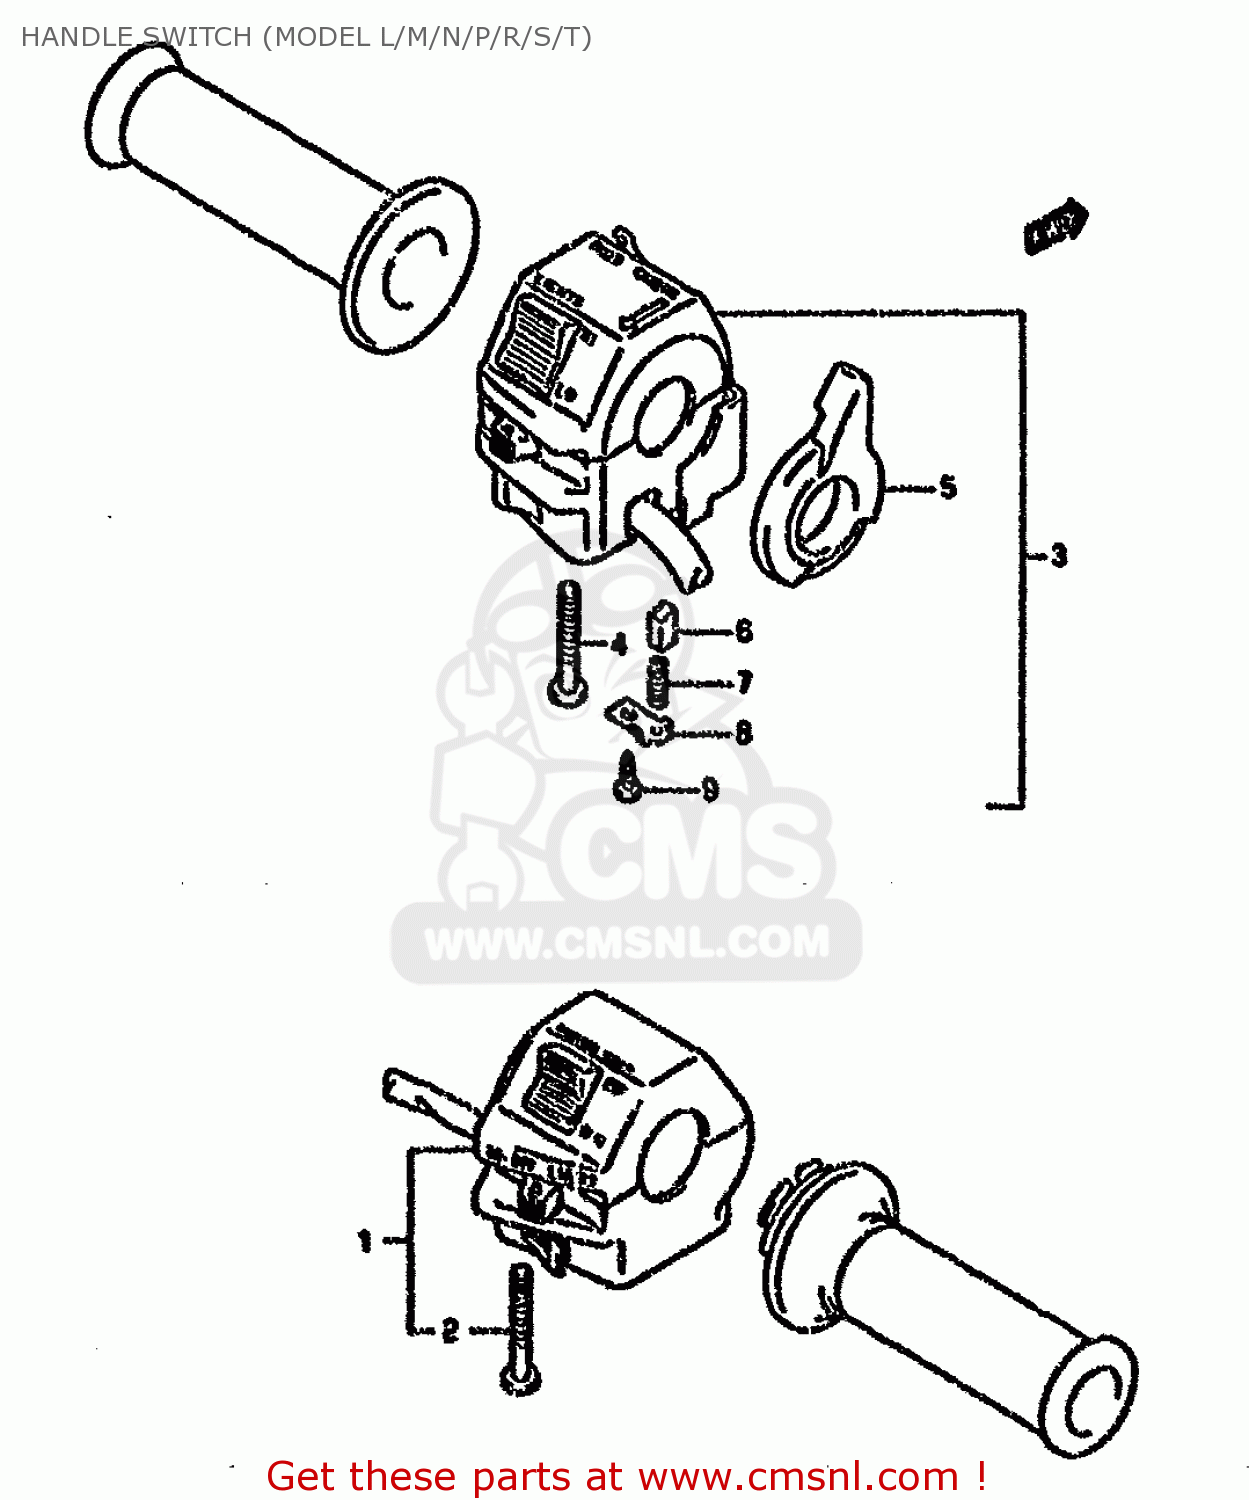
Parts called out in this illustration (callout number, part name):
1	SWITCH,HANDLE
2	SCREW, 5X45
3	SWITCH,HANDLE
4	SCREW, 5X45
5	LEVER,CHOKE
6	PIECE,SLIDE
7	SPRING
8	PLATE
9	SCREW, TRUNK BOX
